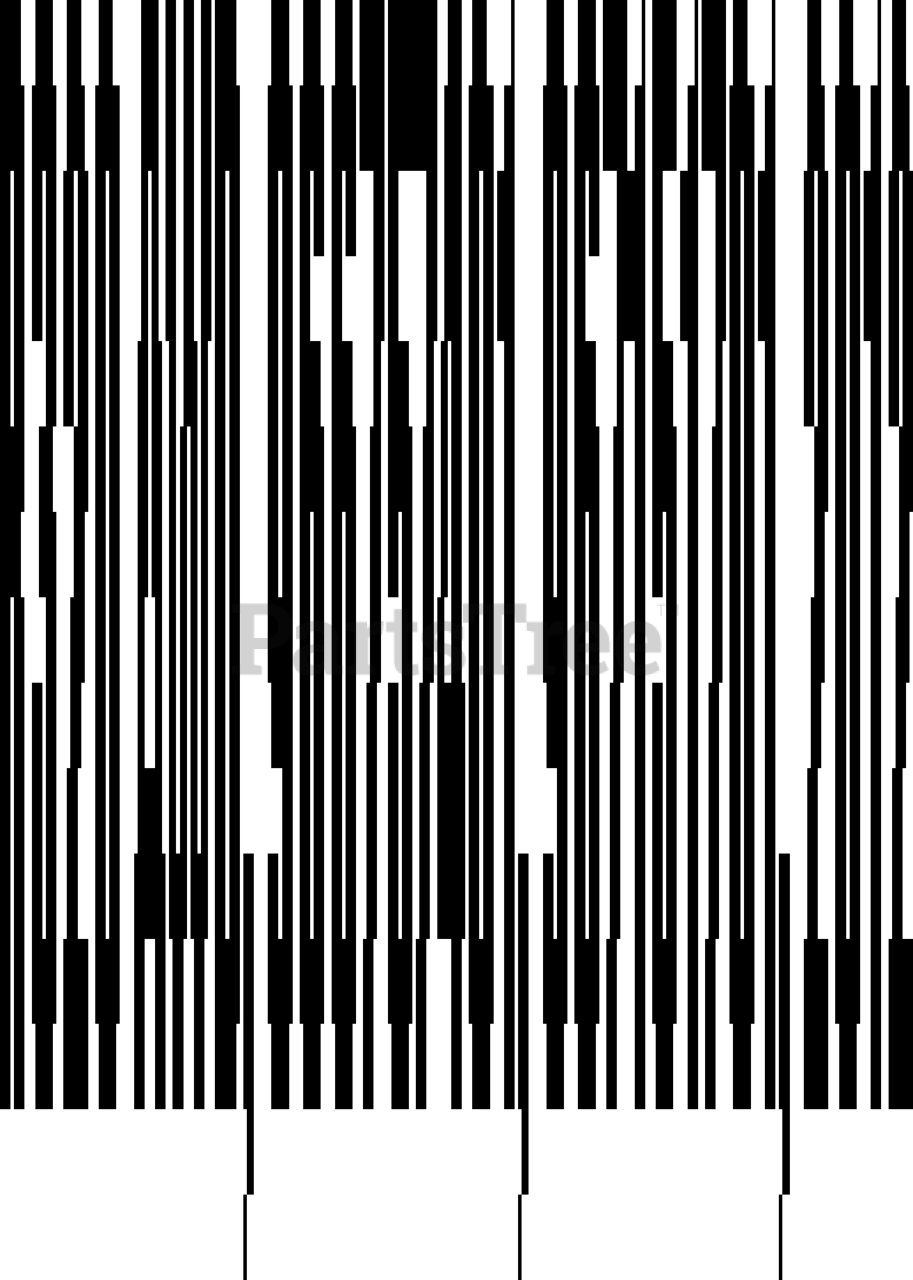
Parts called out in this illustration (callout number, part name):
1	SEAT BRACKET 300 ASSY GREY
2	Screw M10x25
3	SEAT SPRING
4	Screw M10x25
4	WASHER
5	SCREW
6	SEAT ASSY KIT HIGH HVA
6	SEAT HUSQVARNA HIGH BACK
7	SCREW IHSCM
9	SEAT ADJUSTER LEFT & RIGHT
10	LOCKNUT M8
11	SPACER
12	WASHER
13	ADJUSTING KNOB
14	BOLT
15	SEAT BRACKET
